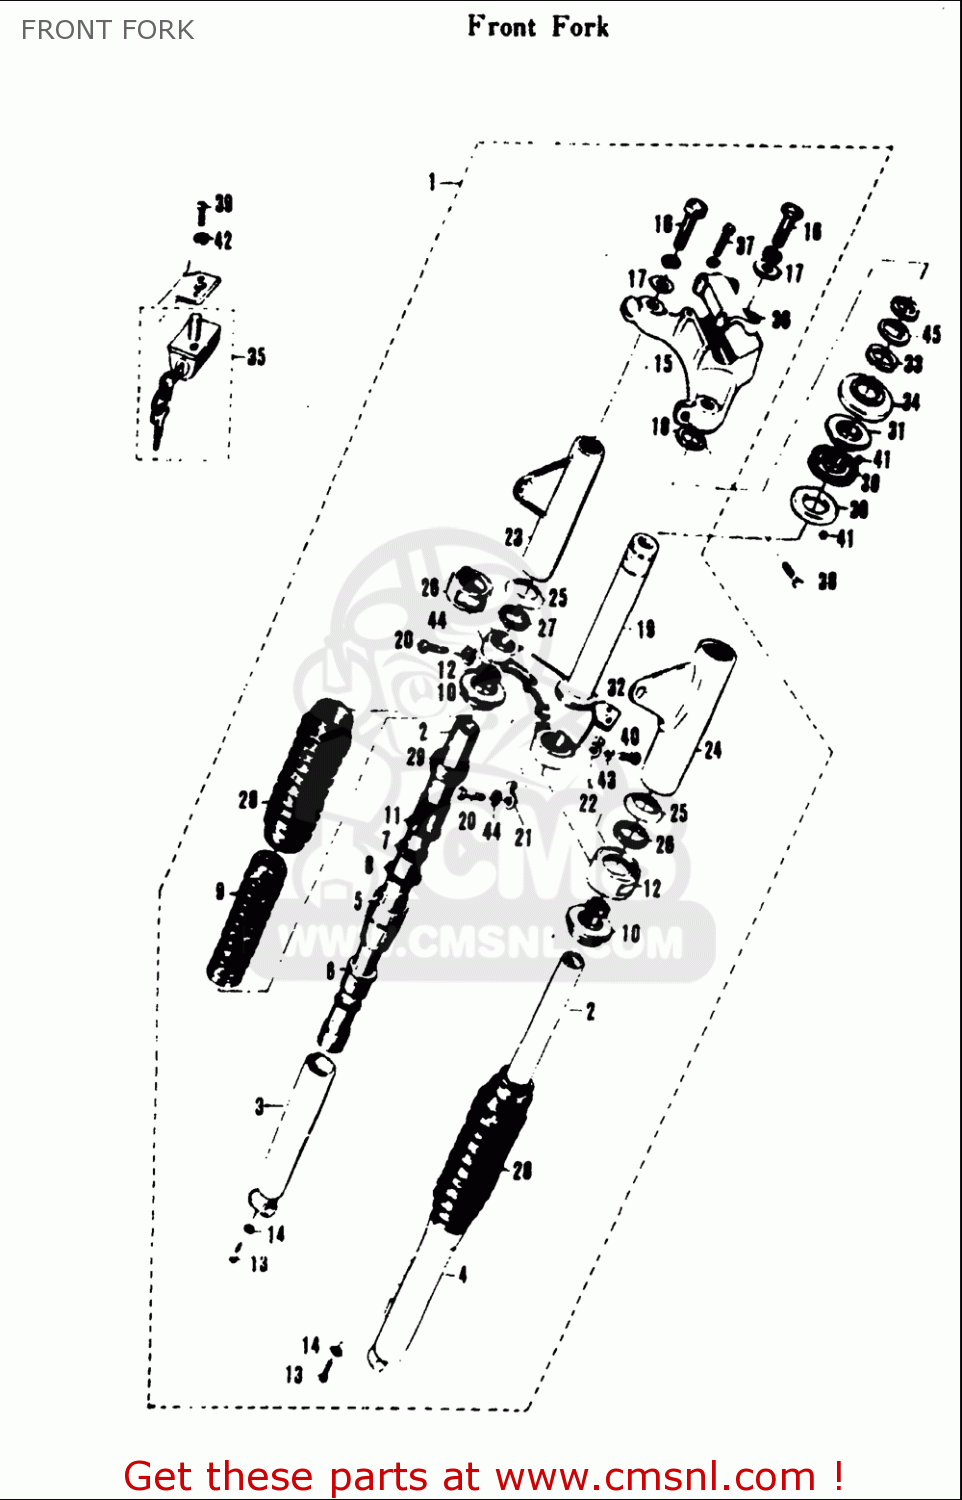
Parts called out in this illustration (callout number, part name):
6	GUIDE,FORK INNER TUBE
13	OIL DRAIN PLUG
14	GASKET,DRAIN,PLUG (NAS)
16	BOLT,FR FORK
17	WASHER,STEERING STEM HEAD
20	BOLT
21	CLIP,SPEEDOMETER CABLE
22	CLIP,BRAKE CABLE
31	LACE,STEERING OUTER UPR
37	BOLT
38	BOLT
42	WASHER,LOCK
43	WASHER,LOCK
44	WASHER,LOCK
